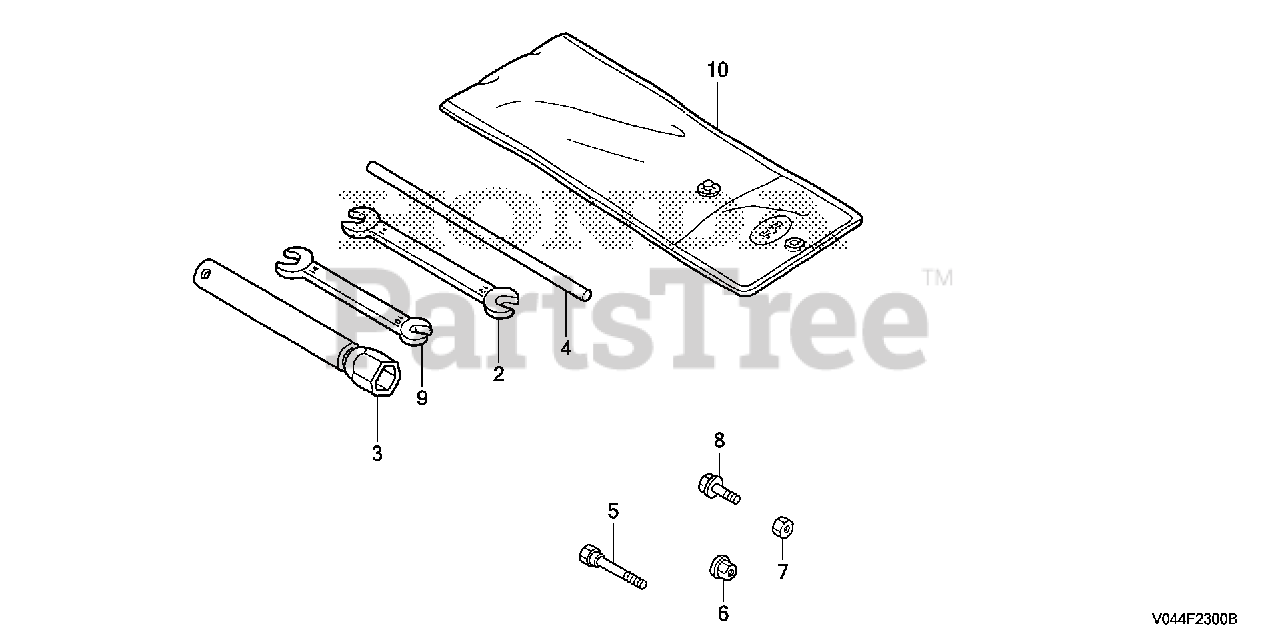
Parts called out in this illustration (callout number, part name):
1	TOOL KIT (NOT AVAILABLE)
2	SPANNER (12X14)
3	WRENCH, SPARK PLUG (NOT AVAILABLE)
4	HANDLE, BOX WRENCH (NOT AVAILABLE)
5	BOLT, LOCK
6	NUT, SELF-LOCK (6MM)
8	BOLT, HEX. (6X16)
9	WRENCH (10X14) (OPEN END)
10	BAG, TOOL
